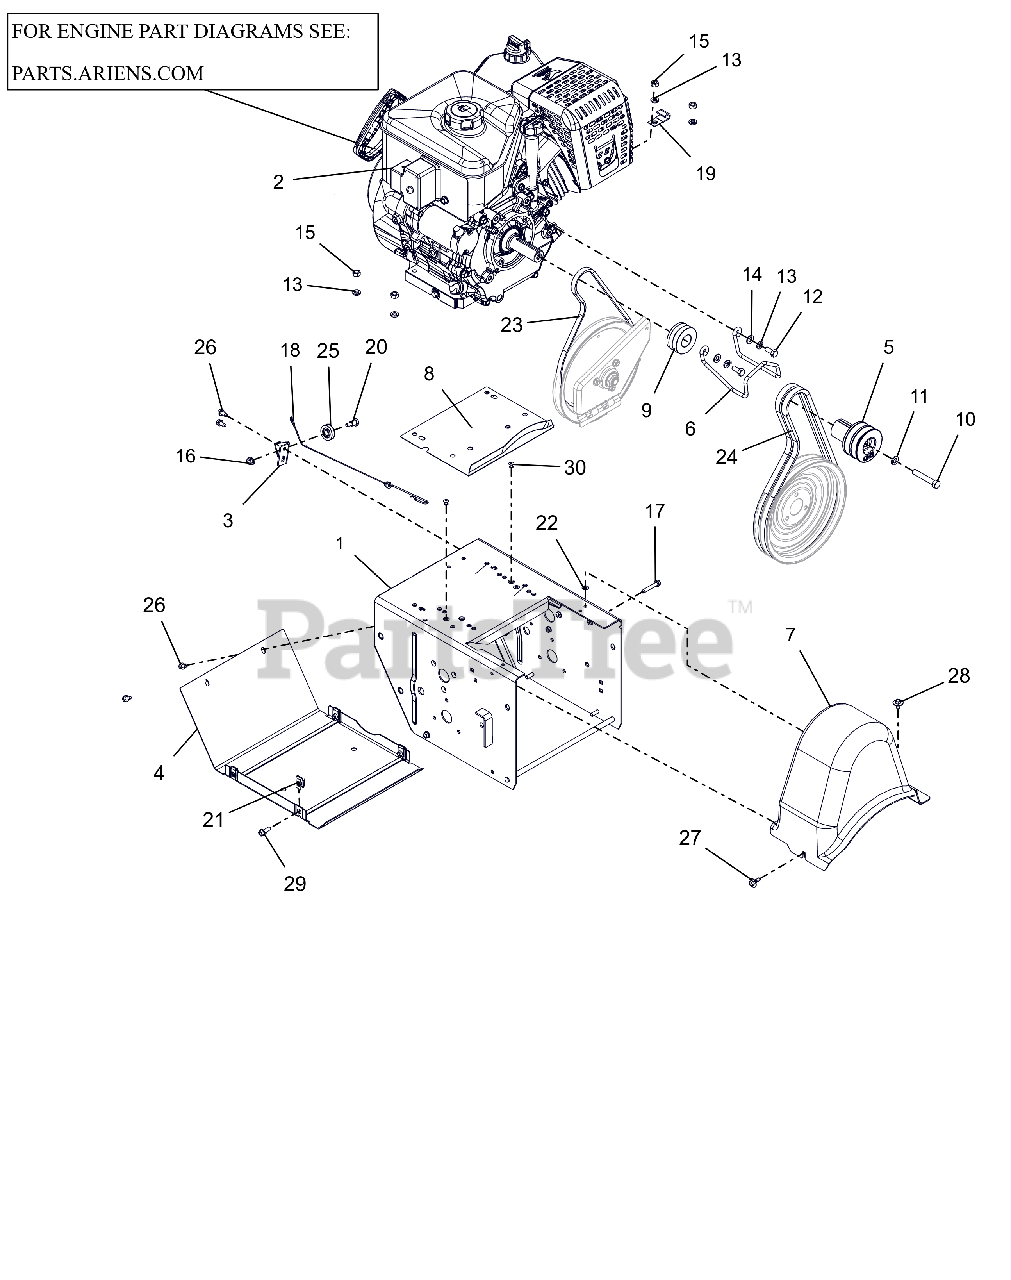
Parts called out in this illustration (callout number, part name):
1	FRAME, MAIN-DELUXE(WELDMENT)
2	ENGINE, AX369 GEN3 120V/60W
3	BRACKET, CABLE PULLEY
4	COVER, BOTTOM
5	SHEAVE,ATTACHMENT-SHO 2 GRV
6	FINGER, BELT
7	COVER, BELT-LARGE
8	BAFFLE, WATER - LARGE BLOCK
9	SHEAVE, TRACTION (KEYLESS)
10	BLT, HEX .38-24X2.25 G5 ZCC
11	WSHR,LK-REG .375X.094 ZCC
12	BLT, HEX .31-24X.750 G5 ZCC
13	WSHR, LK-HVY .312X.097 ZCC
14	WSHR,FLT .344X.688X.065 ZCC
15	NUT, HEX .312-18 ZCC
16	NUT-LK-TOP-FLG .250-20 GF ZCC
17	SCR,TAP .25-20X1.50 HWH TR ZCC
18	CABLE, LOWER TRACTION,SS & PRO
19	J-CLAMP
20	BOLT, SHLDR -.375 X .375 X .25-20
21	NUT-RTNR .25-20X.56
22	NUT-PUSH .25X.50 O.D.
23	V-BELT, 3L-WRAPPED
24	V-BELT, HA-RAW EDGE (SET)
25	PULLEY, CABLE
26	SCR-TAP .25-20X.50 HWH ZCC
27	SCR-TAP .25-20X.5 CAPTIVE
28	SCR, TAP .25-20X.50 LG HWH ZCC
29	BLT, HWH .25-20X.75 G5 ZCC
30	RVT, POP .1875 ZCC
